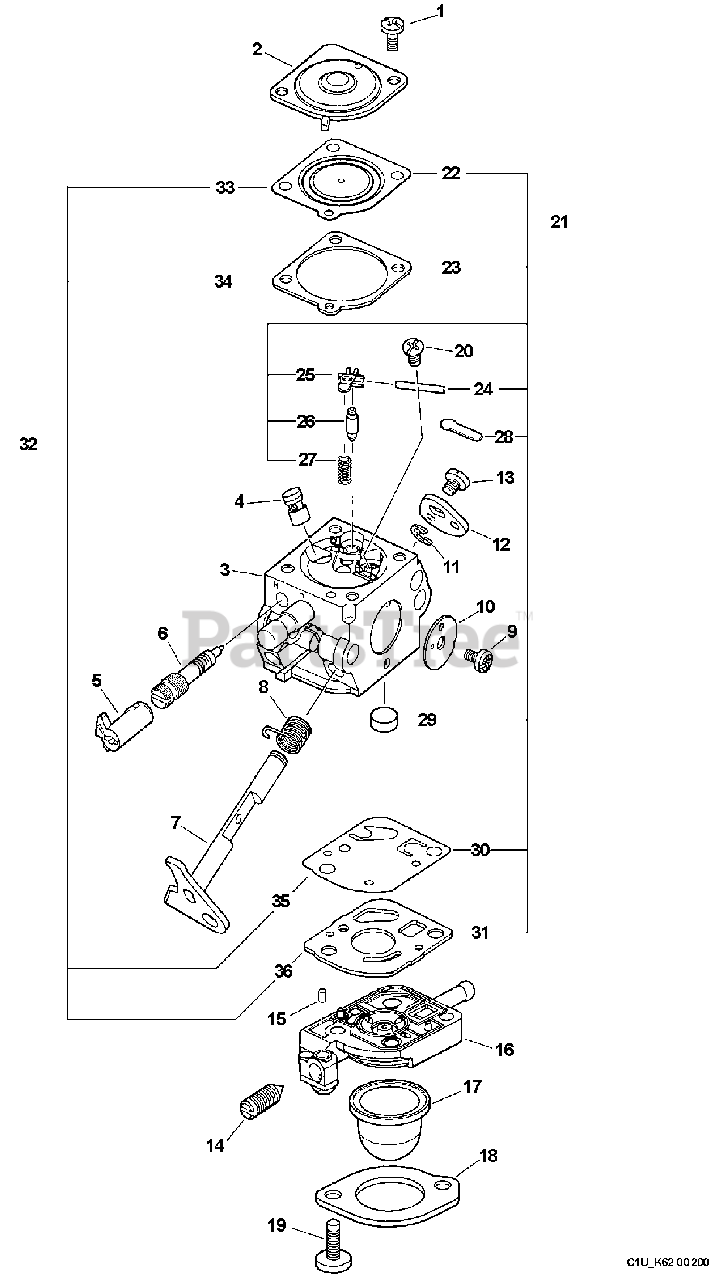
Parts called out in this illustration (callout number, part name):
2	COVER, METERING DIAPHRAGM
3	BODY, CARBURETOR
4	NOZZLE, CHECK VALVE
5	CAP, LIMITER
6	NEEDLE, HIGH SPEED
7	SHAFT ASSY, THROTTLE
8	SPRING, THROTTLE RETURN
10	VALVE, THROTTLE
12	LEVER, THROTTLE
15	PIECE, FRICTION
16	BODY ASSY, PURGE
17	BULB, PURGE
18	RETAINER
21	REPAIR KIT
22	DIAPHRAGM, METERING
23	GASKET, DIAPHRAGM
24	PIN, METERING LEVER
25	LEVER, METERING
26	VALVE, INLET NEEDLE
27	SPRING, METERING LEVER
28	PLUG, WELCH
29	STRAINER
30	DIAPHRAGM, PUMP
31	GASKET, PUMP
32	GASKET / DIAPHRAGM KIT
33	DIAPHRAGM, METERING
34	GASKET, DIAPHRAGM
35	DIAPHRAGM, PUMP
36	GASKET, PUMP
